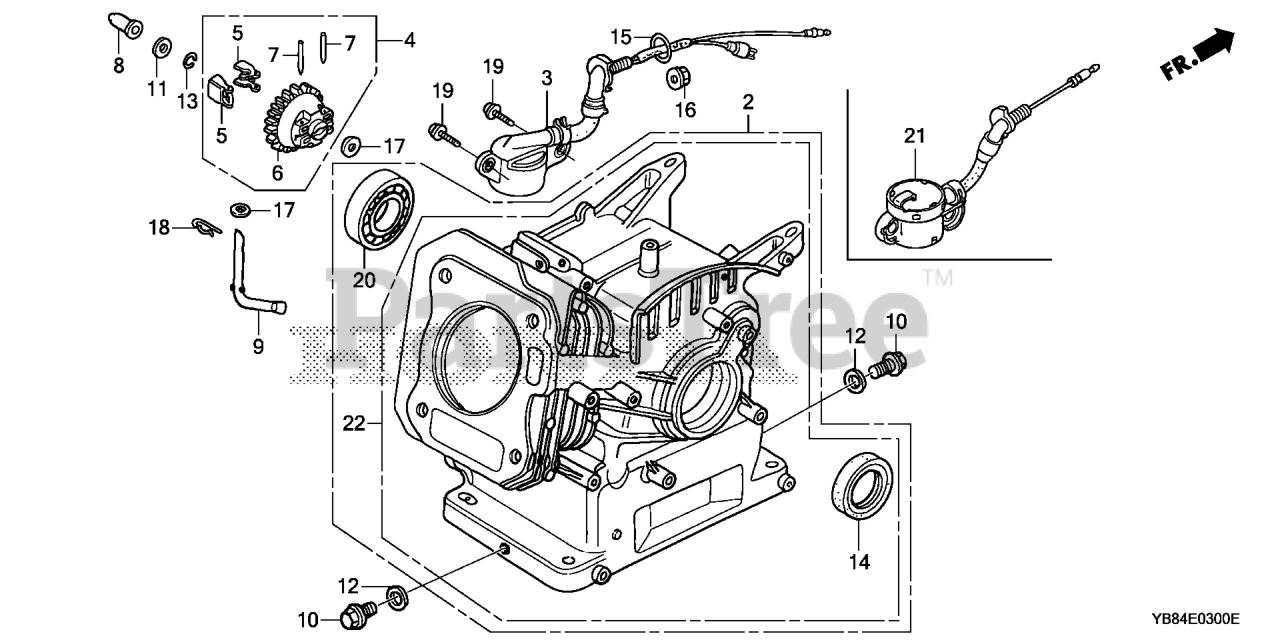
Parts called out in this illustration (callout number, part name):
4	GOVERNOR ASSY.
5	WEIGHT, GOVERNOR
6	HOLDER, GOVERNOR WEIGHT
7	PIN, GOVERNOR WEIGHT
8	SLIDER, GOVERNOR
9	SHAFT, GOVERNOR ARM
10	BOLT, DRAIN PLUG
12	WASHER, DRAIN PLUG (10.2MM)
13	CLIP, GOVERNOR HOLDER
14	OIL SEAL (25X41X6)
14	OIL SEAL (25X41X6) (ARAI) (NOT AVAILABLE)
15	O-RING (14MM) (ARAI) Use up to Engine SN 2949254.
15	O-RING (14MM) (NOK)
16	NUT, FLANGE (10MM)
17	WASHER, PLAIN (6MM)
18	PIN, LOCK (8MM)
19	BOLT, FLANGE (6X12) Use up to Engine SN 1543277.
21	SWITCH ASSY., OIL LEVEL
22	CYLINDER ASSY. (OIL ALERT)
